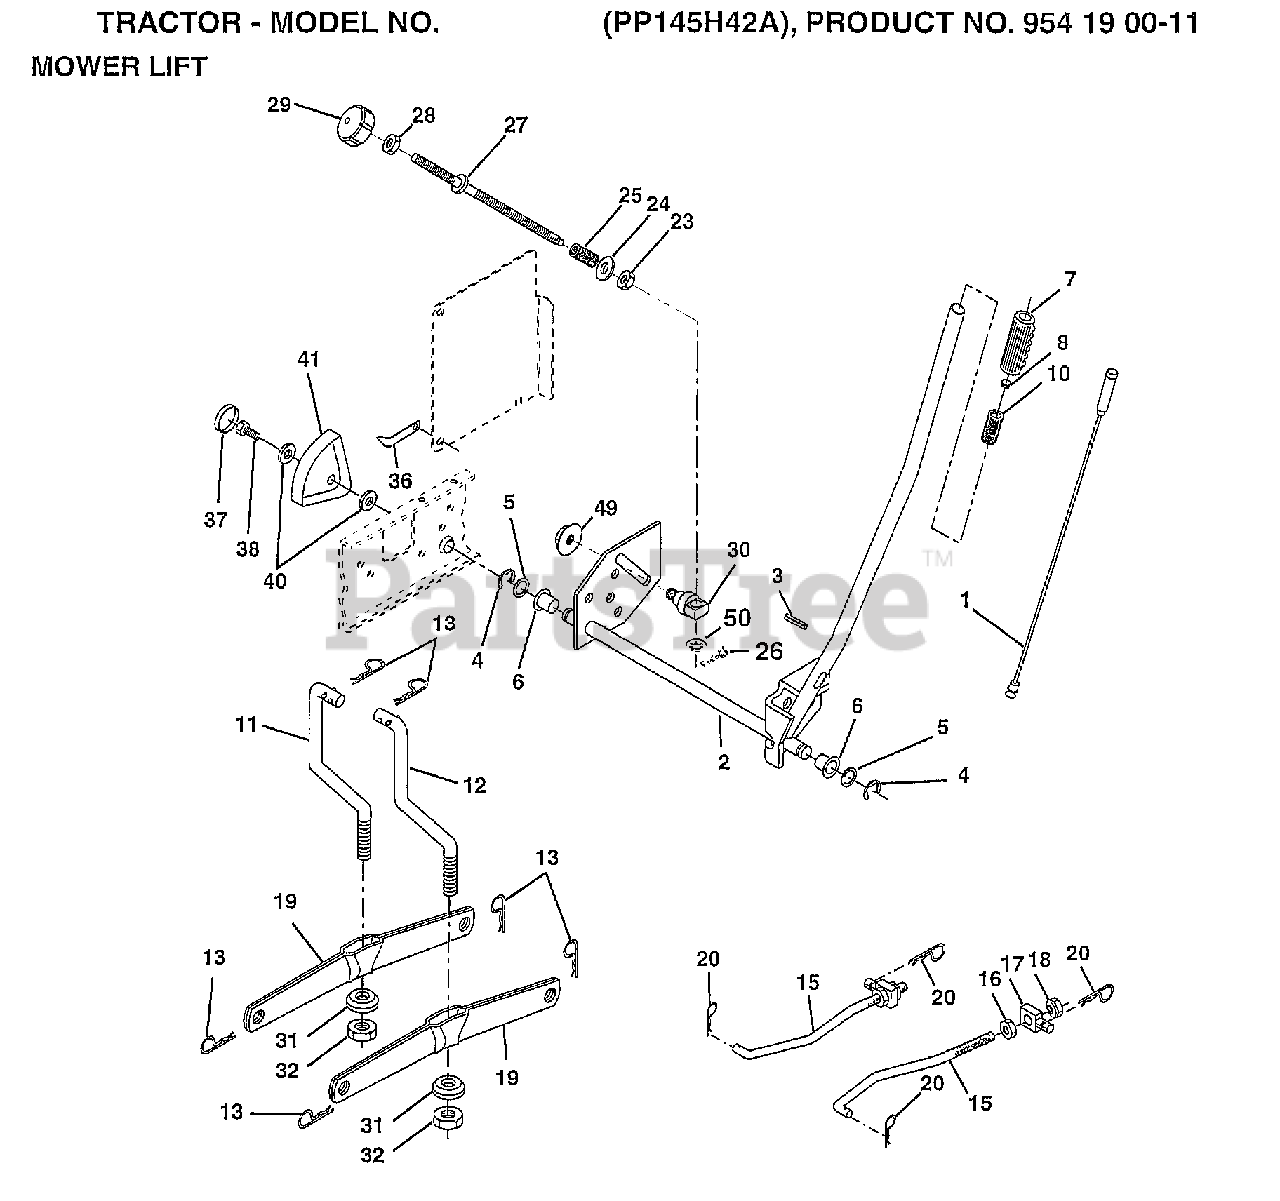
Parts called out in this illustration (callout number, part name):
1	WIRE ASM
2	SHAFT.LIFT.ASM.RH
3	PIN-GROOVE LT
5	WASHER
6	NYLON BEARING
7	GRIP
15	LINK.FRONT
16	NUT
17	TRUNION
18	NUT.LK.W/WSH.1/2.
19	ARM SUSP REAR
20	RETAINER.SPRING
23	NUT T
24	WASHER
25	SPRING T
28	NUT
29	KNOB INF 3/8-16
30	TRUNNION
31	BEARING PVT LH
32	NUT.CROWNLOCK.3/8
36	POINTER-INDICAT
37	"PLUG,HOLE"
38	SCREW
40	WASHER
41	HEIGHT INDICATOR
49	NUT.HXFLG.LOCK.
50	NUT PUSH M
